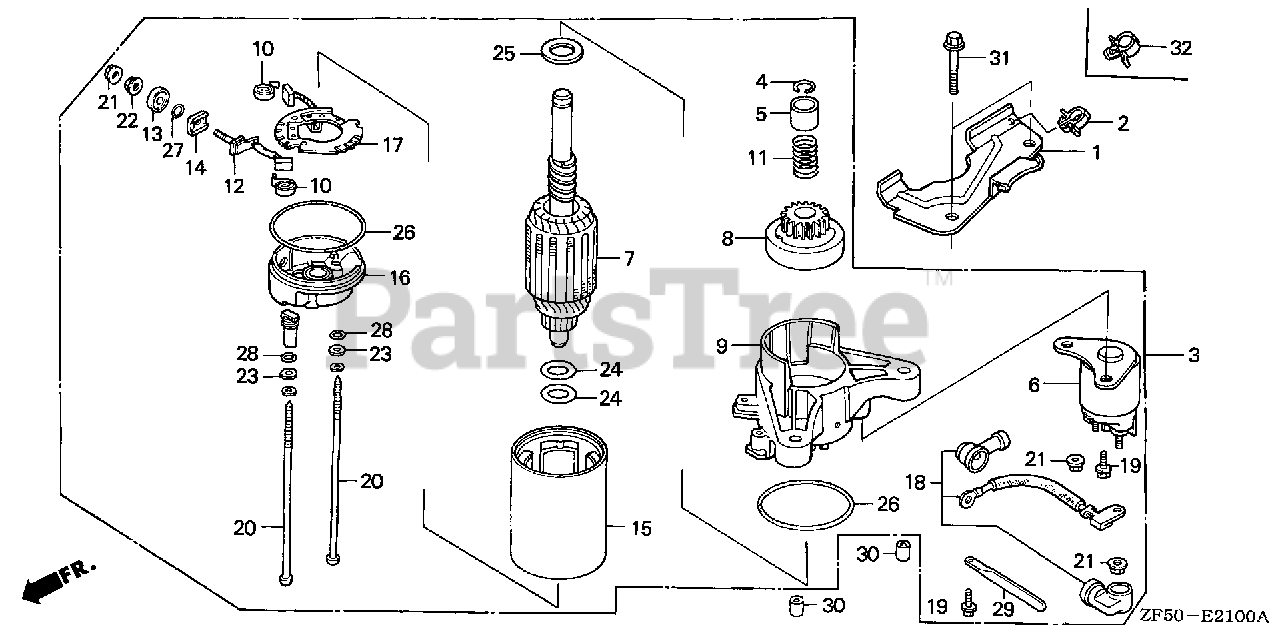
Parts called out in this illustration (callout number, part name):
1	PLATE, SIDE Use up to Engine SN 2013741.
1	PLATE, SIDE
2	CLIP, IGNITION WIRE (8MM)
3	STARTER MOTOR ASSY.
4	RING, SNAP
5	COLLAR, CLUTCH STOP
6	CONTACTOR ASSY.
8	CLUTCH ASSY., OVERRUNNING
9	HOUSING, DRIVE SIDE
10	SPRING, BRUSH
13	BUSH, INSULATION
14	BUSH, INSULATION
16	FRAME, STARTER END
17	PLATE, BRUSH HOLDER
18	WIRE, WATER COVER
19	BOLT
20	BOLT, THROUGH Use up to Engine SN 2008435.
20	BOLT, THROUGH
23	WASHER, STEEL PLATE
24	WASHER
26	O-RING
28	O-RING
29	CLAMP, CORD
30	PIN, DOWEL (10X16)
31	BOLT, FLANGE (8X35)
32	CLIP, BRAKE PIPE (A)
